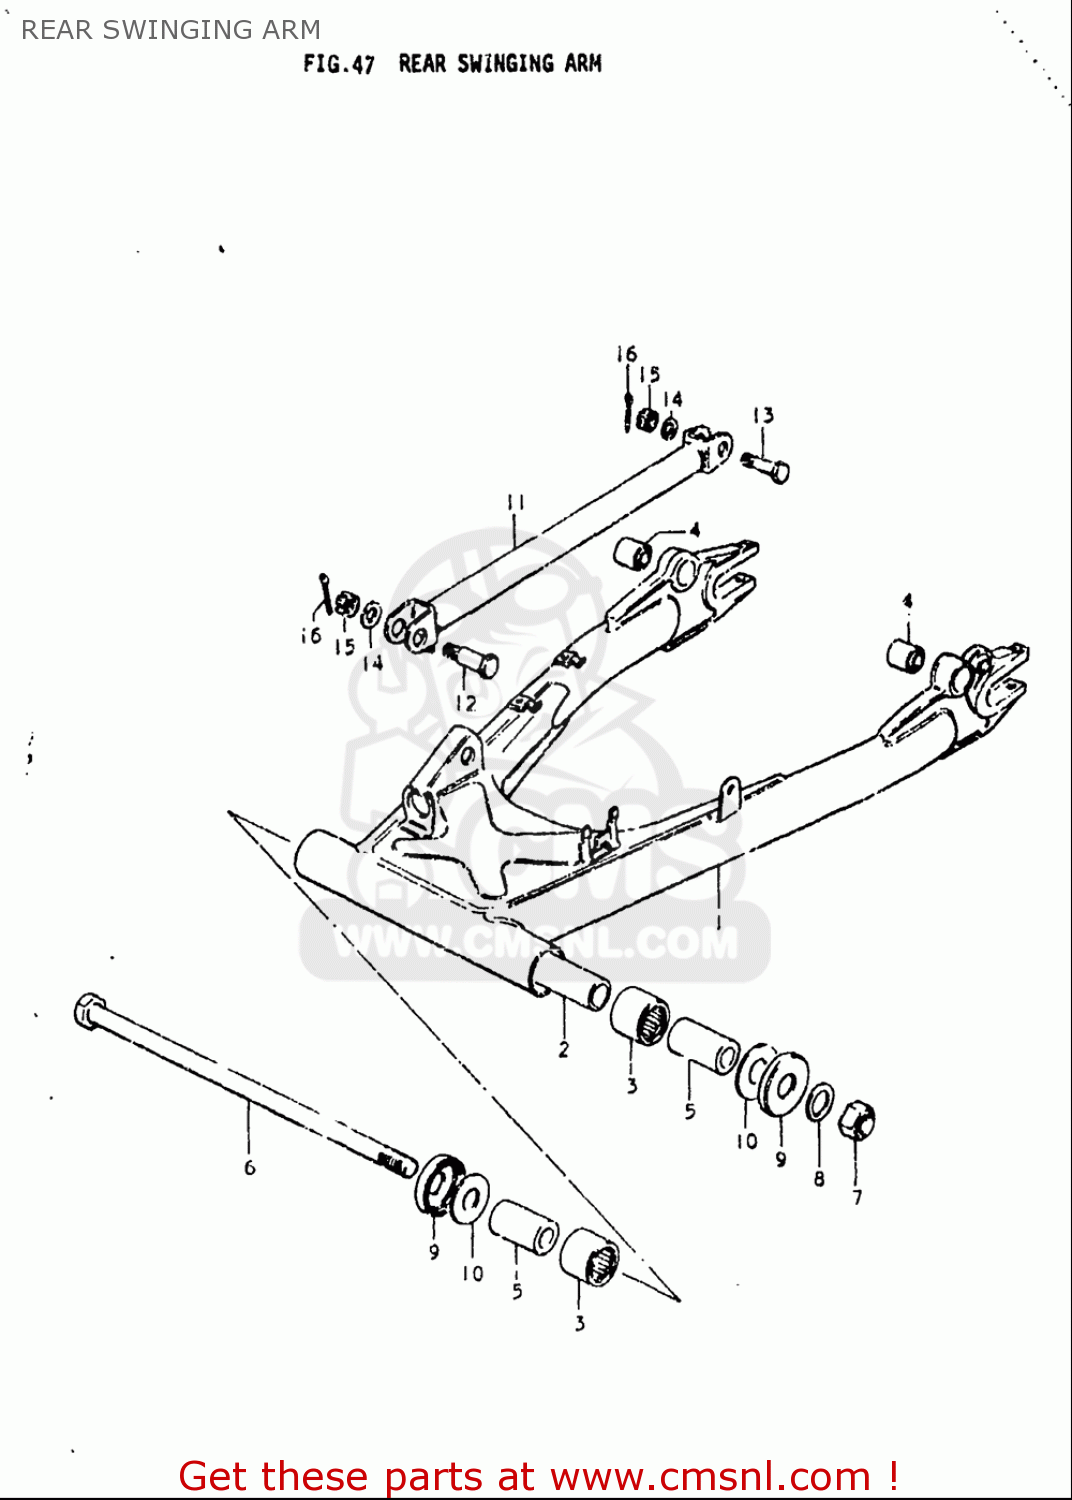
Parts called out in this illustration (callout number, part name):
2	SPACER,RR SWGARM PIVOT CTR
3	BEARING(22X29X30)
4	BUSH
5	SPACER,RR SWGARM PIVOT
6	SHAFT,REAR SWING ARM
7	NUT 14MM
8	WASHER
9	CVR,RR SWGARM DUST SEAL(OD:40)
10	WASHER(14.2X34X1)
12	BOLT M10X39
13	BOLT(10X39)
14	WASHER
15	NUT
16	PIN
